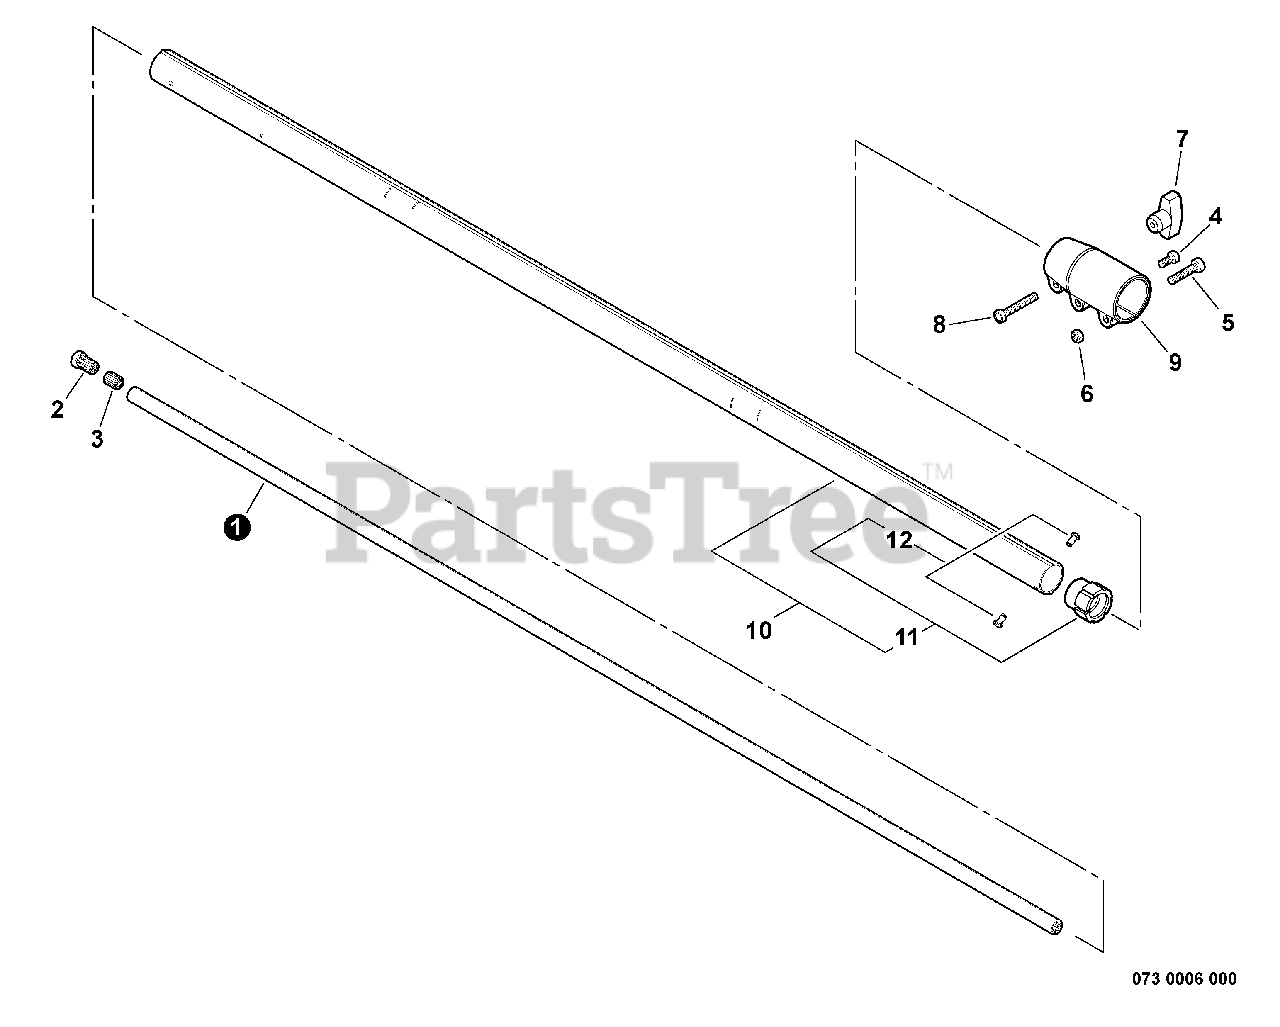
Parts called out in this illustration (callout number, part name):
1	DRIVESHAFT - UPPER
2	SOCKET - OUTER
3	SOCKET - INNER
4	SCREW - 5X10
5	SCREW - 5X20
7	THUMBSCREW
8	BOLT - 6X25
9	COUPLING
10	MAIN PIPE ASSY - BLACK
11	BEARING HOLDER ASSY
